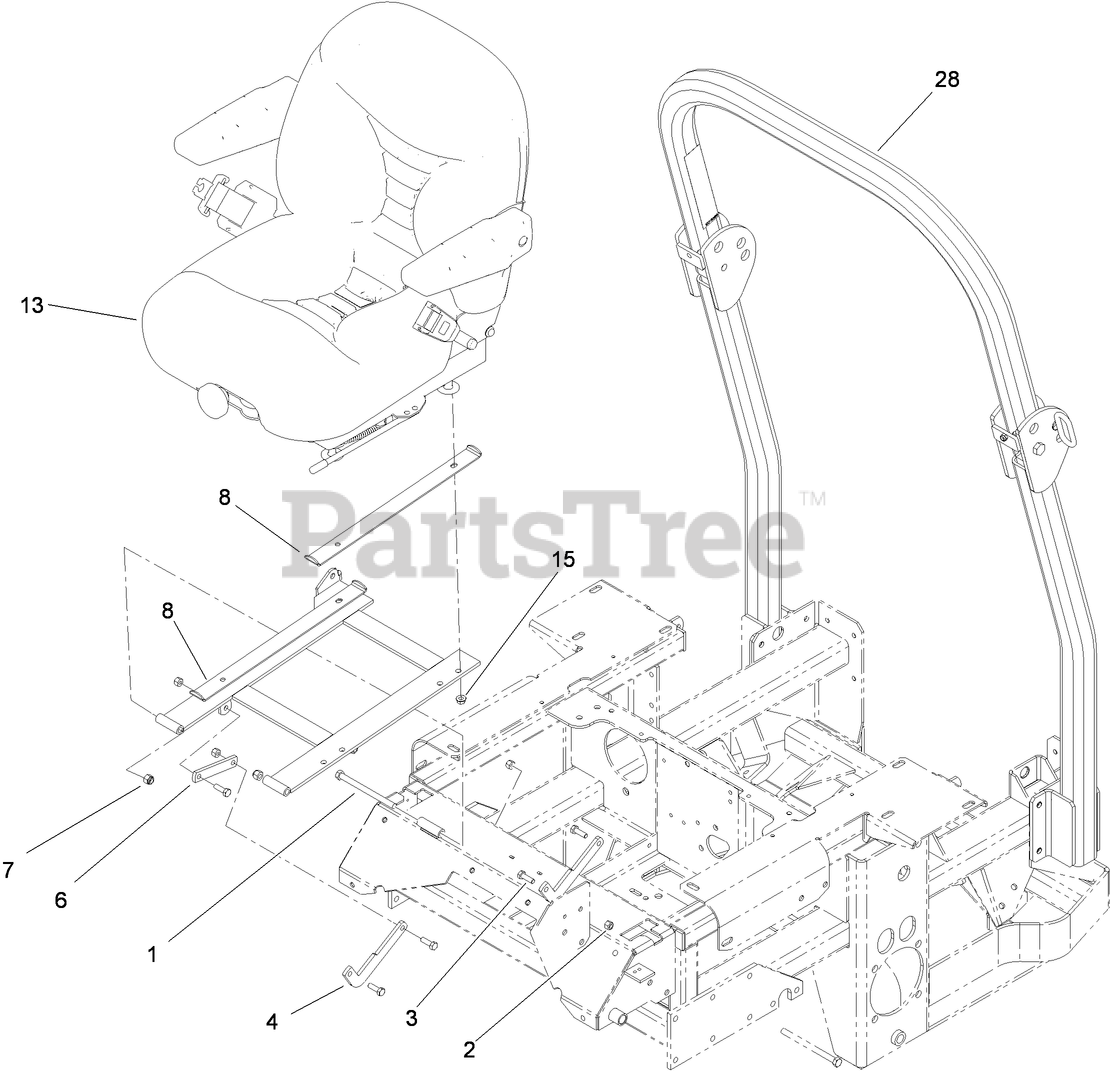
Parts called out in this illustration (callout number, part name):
1	SCREW-HH
2	NUT-LOCK, NI
3	SCREW-HH
4	LINK-STOP, SEAT
6	LINK-STOP, SEAT
7	NUT-LOCK, NI
8	STOP-SEAT
13	DELUXE SEAT ASM
15	NUT-HF
28	ROPS ASM
